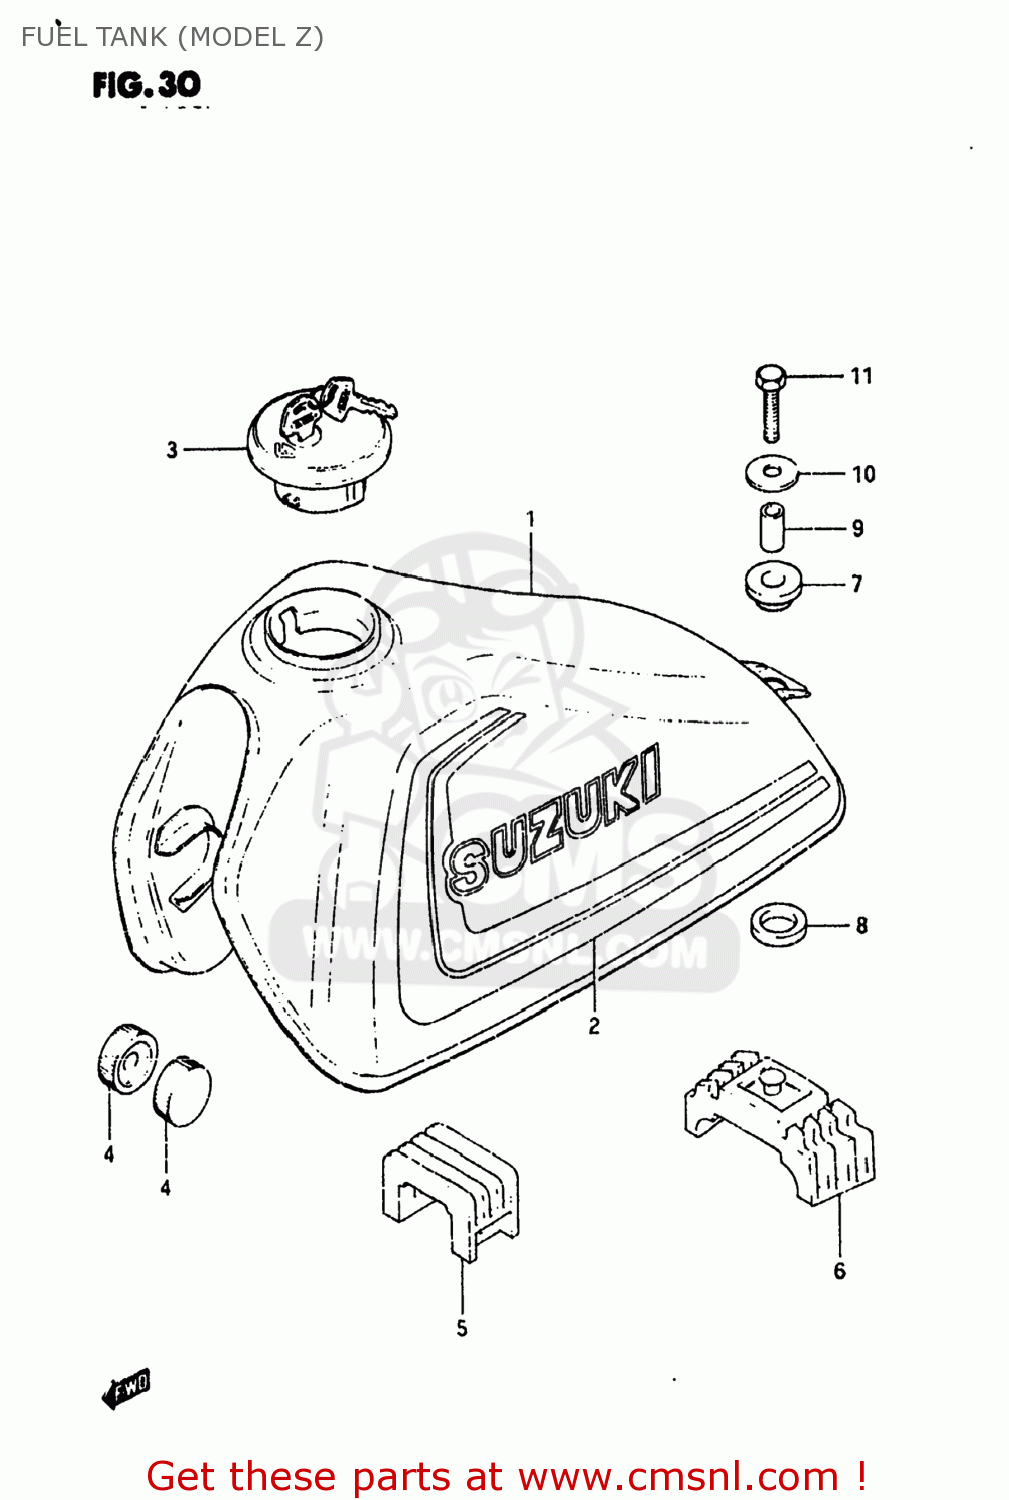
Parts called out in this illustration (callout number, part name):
1	TANK ASSEMBLY,FUEL
2	TAPE SET,FUEL TANK
3	CAP SET,FUEL TANK
4	CUSHION
5	CUSHION,TANK UPR FR
6	CUSHION,FUEL TANK,REAR
7	CUSHION
8	CUSHION
9	SPACER(8.5X12X19)
10	WASHER (8.5X29X1.6)
11	BOLT (8X30)
